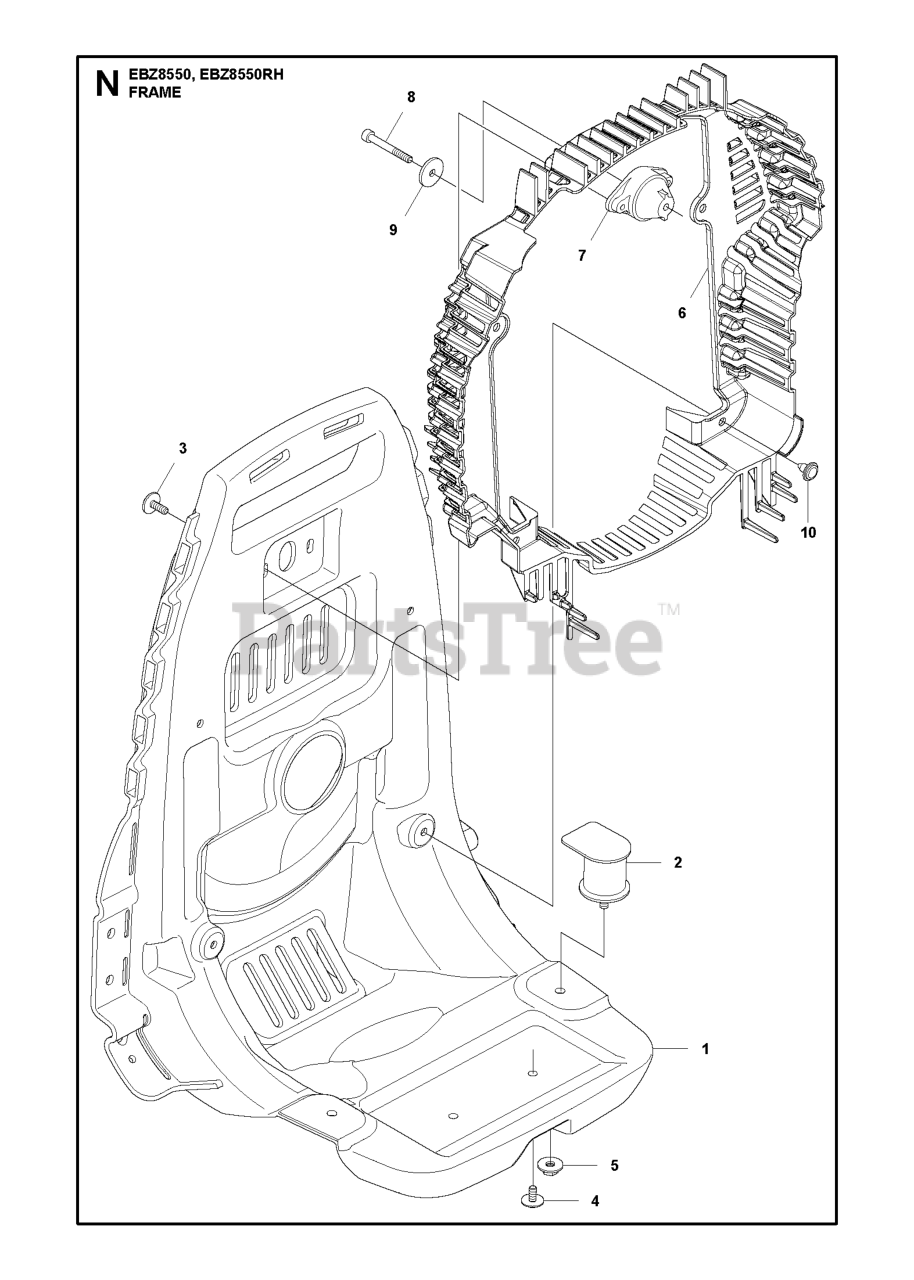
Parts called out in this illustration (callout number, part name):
6	NET ASSY
8	BOLT
10	CLIP
